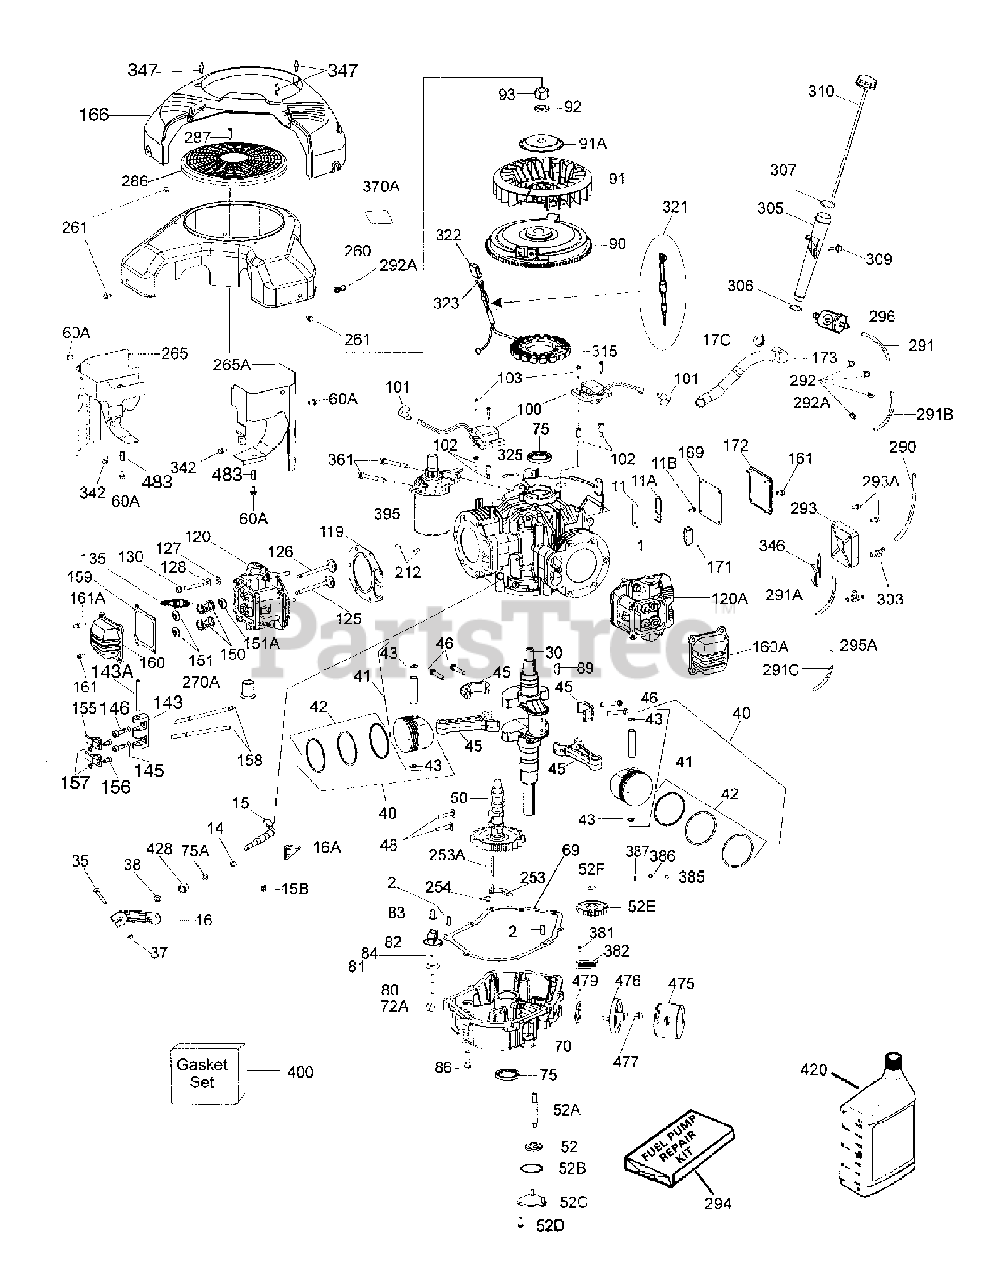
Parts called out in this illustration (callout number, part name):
11A	Breather Plate
11B	Screw, 10-32 x 7/16"
15	Governor Rod
15B	Screw, 1/4-20 x 5/8"
16	Governor Lever
16A	Governor Spring Bracket
17C	Breather Tube Clamp
35	Screw, Carriage 1/4-20 x 1-1/2"
37	Lock Nut, 1/4-20
38	Retaining Ring
40	Piston, Pin & Ring Set (Std.)
40	Piston, Pin & Ring Set (.010" OS)
41	Piston & Pin Ass'y. (Std.) (Incl. 43)
41	Piston & Pin Ass'y.(.010" OS) (Incl. 43)
42	Ring Set (Std.)
42	Ring Set (.010"OS)
43	Piston Pin Retaining Ring
45	Connecting Rod Ass'y. (Incl. 46)
46	Connecting Rod Bolt
48	Valve Lifter
50	Camshaft (MCR)
52	Oil Pump Ass'y.
52A	Oil Pump Shaft
52C	Oil Pump Cover (Incl. 52B)
52D	Screw, T-30 1/4-20 x 43/64"
52E	Oil Pump Gear
52F	Oil Pump Gear Retaining Ring
60A	Screw, 1/4-20 x 1/2"
69	Mounting Flange Gasket Kit (P)
70	Mounting Flange (Incl.72,72A,75,80,381-387)
72A	Oil Drain Plug
75	Oil Seal (1 in Ref 1, 1 in Ref 70)
75A	Oil Seal (Governor Shaft)
80	Governor Shaft
81	Washer (Governor Shaft)
82	Governor Gear Ass'y.
83	Governor Spool
84	Retaining Ring
86	Screw, 5/16-18 x 1-15/32"
90	Flywheel (Incl. 91 & 91A)
91A	Flywheel Retainer
92	Belleville Washer
100	Solid State Ignition (Incl. 101)
101	Spark Plug Cover
102	Solid State Mounting Stud
103	Screw, T-15 10-24 x 15/16"
119	Cylinder Head Gasket Kit (P)
120	Cylinder Head, Opp. Breather Side
120A	Cylinder Head, Breather Side
125	Exhaust Valve (Std.)
126	Intake Valve (Std)
128	Belleville Washer
130	Screw, 5/16-18 x 2-1/2"(Head Mount)
135	Spark Plug (RN4C)
143	Rocker Arm Housing
143A	Rocker Arm Pin
146	Screw, T-45 5/16-24 X 29/32"
150	Valve Spring
151	Valve Keeper Retainer & Cap Set
151A	Valve Seal
156	Adjusting Screw
159	Rocker Arm Cover Gasket Kit (P)
160	Rocker Arm Cover
160A	Rocker Arm Cover
161	Screw, T-30 1/4-20 x 1/2"
161A	Stud, Valve Cover Mounting
166	Engine Shroud
169	Valve Cover Gasket Kit (P)
171	Breather Element
173	Breather Tube
253	Compression Release Weight
253A	Compression Release Pin
254	Compression Release Spring
260	Blower Housing (Black)
261	Shoulder Screw
265	Cylinder Head Cover, Opp. Breather
265A	Cylinder Head Cover, Breather Side
270A	Exhaust Port Liner
286	Flywheel Screen
287	Screw, T-20 8-18 x 1-15/32"
290	Fuel Line (16.75")
291A	Fuel Line (8-1/4")
291B	Fuel Line
291C	Fuel Line (6.75")
292	Fuel Line Clamp
292A	Fuel Line Retainer
293	Pulse Pump
293A	Screw, 8-32 x 1-1/2"
295A	Fuel Fitting
296	Fuel Filter (Incl. 292)
303	Pulse Pump/Fuel Fitting
305	Oil Fill Tube
306	O-Ring (Oil Fill, Bottom) Kit (P)
307	O-Ring (Oil Fill, Top)
309	Screw, 1/4-20 x 57/64"
315	Alternator Coil (16 Amp) (Incl.322-323B)
322	Connector Body
342	Screw, 1/4-20 x 9/16"(Ref. 240 & 265)
346	Fuel Pump Bracket
347	Screw (without air duct)
347	Stud (with air duct)
361	Screw, 5/16-18 x 2-3/8"
370A	Lubrication Decal
381	Screw, 8-32 x 27/64"
382	Oil Strainer Screen
386	Pressure Release Spring
395	Electric Starter Motor (12 Volt)
400	Gasket Set (Incl. Items Marked PK in Notes)
476	Oil Filter Adaptor (Incl. 479)
477	Screw, T-30 5/16-18 x 1 3/32"
479	Oil Filter Adaptor Gasket Kit (P)
